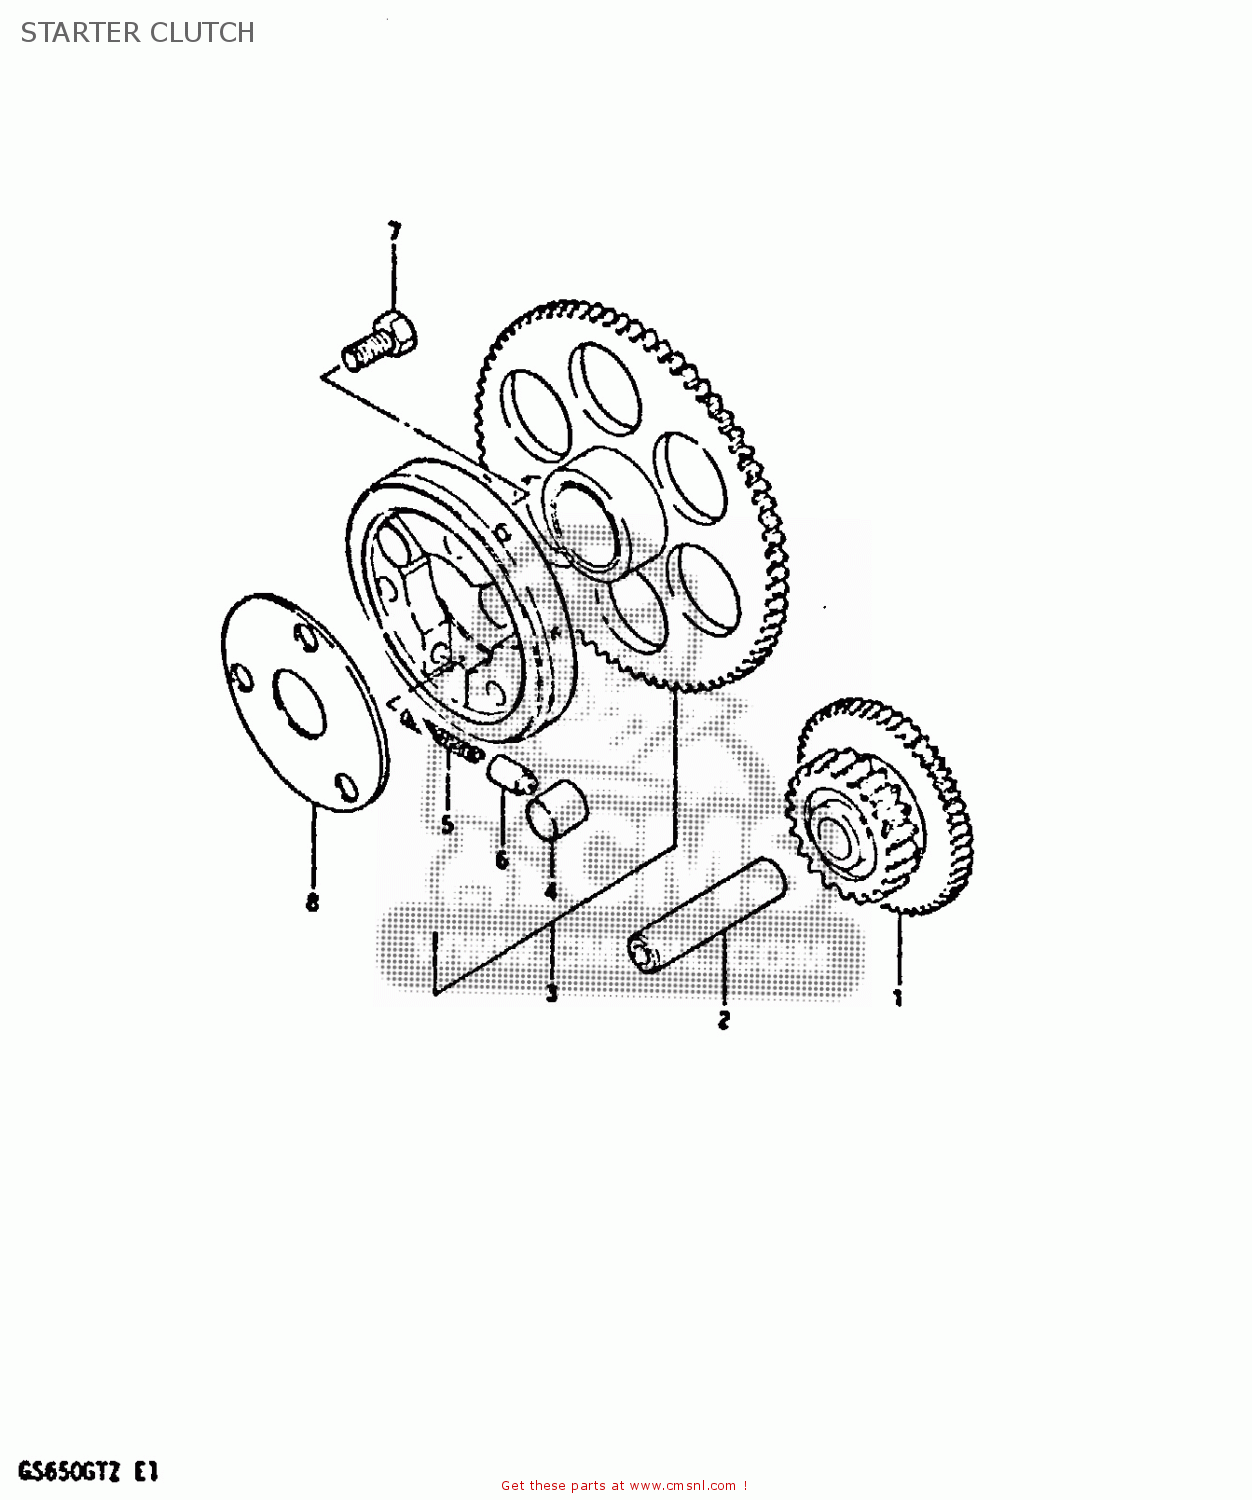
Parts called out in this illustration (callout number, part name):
1	GEAR,STARTER IDLE
2	PIN(7.4X13X56)
3	CLUTCH SET,STARTER
4	ROLLER(15X13)
5	SPRING
6	PIECE,PUSH
7	BOLT
8	SHIM,STARTER CLUTCH HUB
